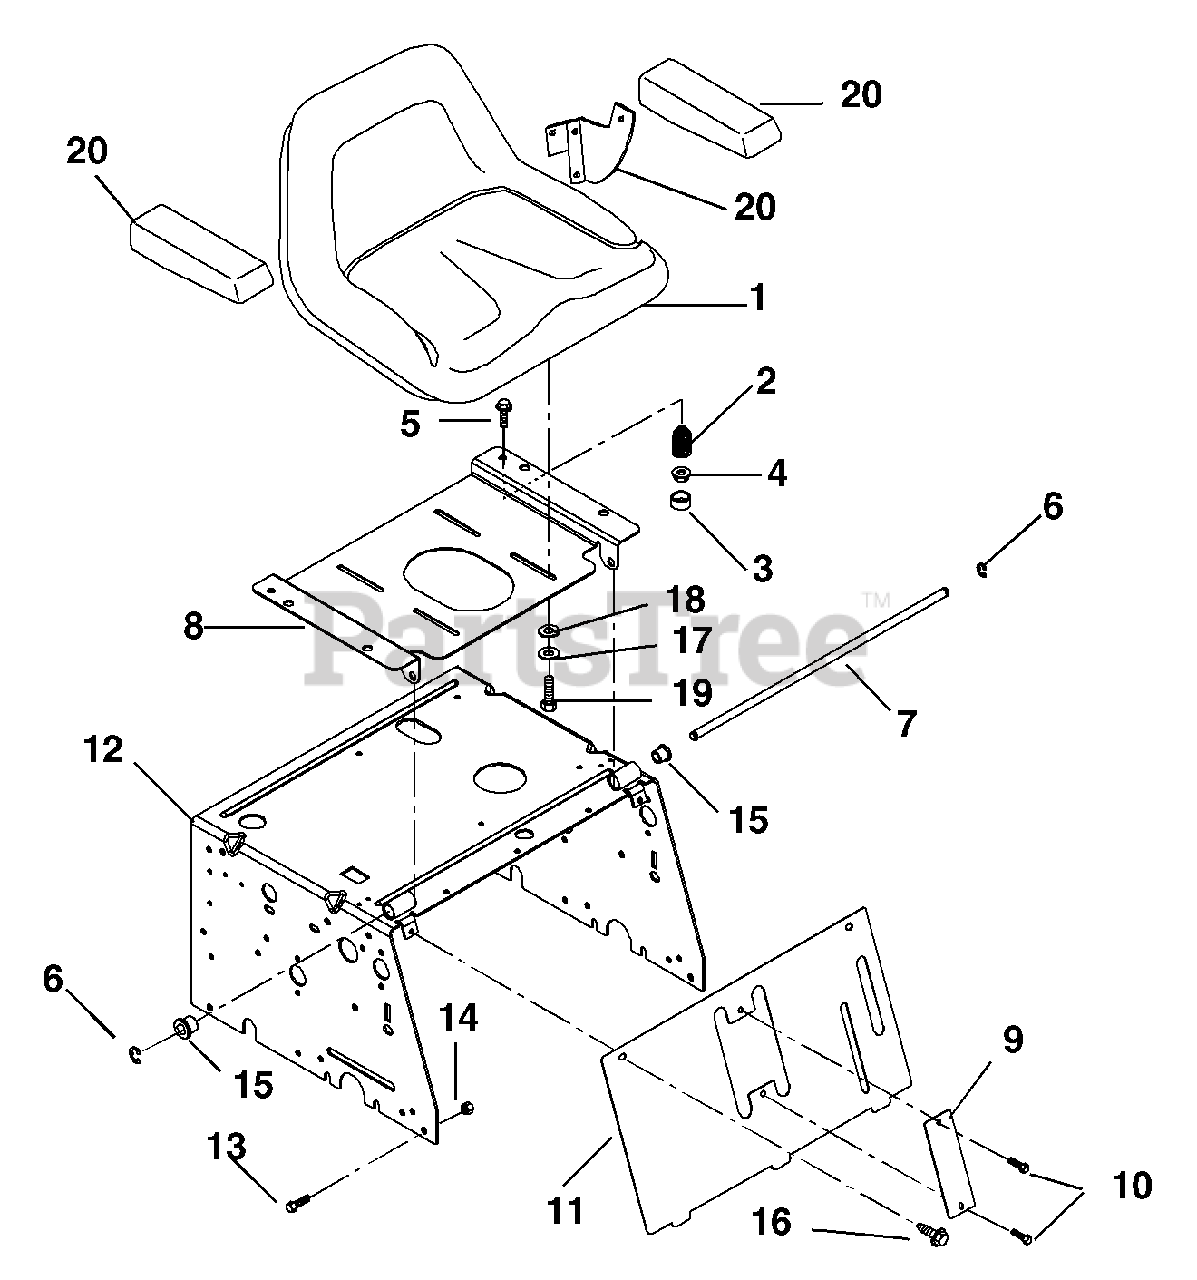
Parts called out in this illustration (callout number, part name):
2	Spring-Compression 2.9L x 2.02 OD
3	Boot-Seat Spring
4	Nut-Locking, Flange .375-16
5	Bolt-Hex Flanged Whiz Lock Head .38-16 x .75
6	Ring-Retaining-External .500 x .042
7	Axle-Front
8	Plate-Seat
10	Bolt-Hex .25-20 x .50 Grade 5
11	Panel-Weldment
12	Support-Seat Weldment
13	Bolt-Hex .38-16 x 1.00 Grade 5
14	Nut-Locking .375-16 Grade A
15	Bushing-Flange
16	Screw, Tapping .31-18 x .75
17	Washer-Lock .31 x .078
18	Washer-Flat-Steel .344 x .688 x .065
19	Bolt-Hex .31-18 x 1.00 Grade 5
20	Arm Rest Kit
20	Arm Rest
20	Bracket-Left Hand Armrest
20	Bracket-Right Hand Armrest
20	Hardware Pack, Armrest Kit
